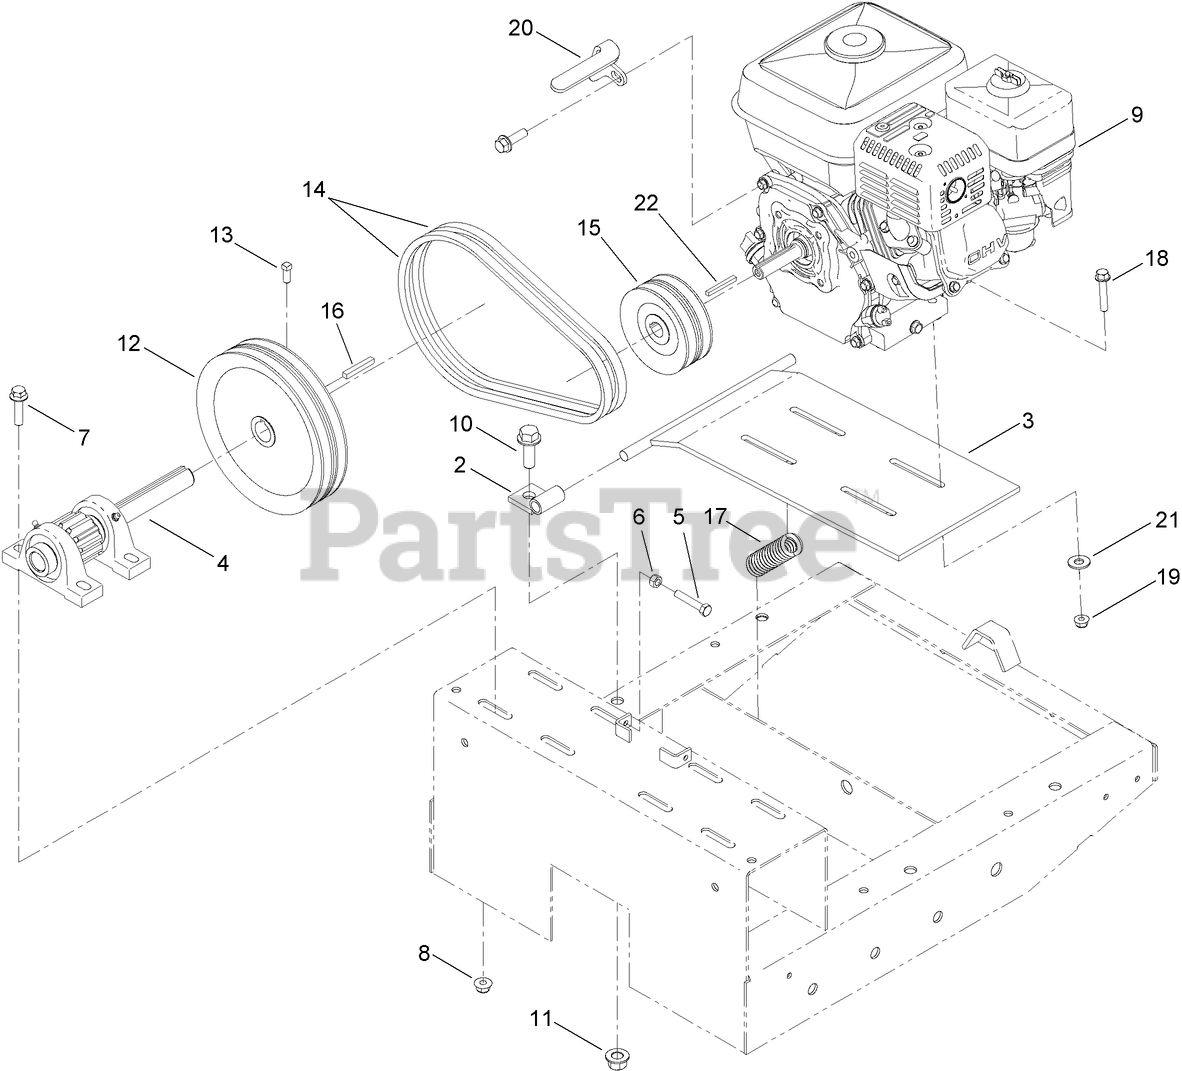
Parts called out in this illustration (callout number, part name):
2	MOUNT-MOTOR
3	BASE-MOTOR
4	PINION ASM
5	SCREW-HH
6	NUT-HEX
7	SCREW-HHF
8	NUT-HF, NI
9	ENGINE-HONDA, GX160
10	SCREW-HHF
11	NUT-LOCK
12	SHEAVE
13	SCREW-SET, SQH
14	BELT-V
15	SHEAVE
16	KEY-SQUARE
17	SPRING
18	SCREW-HWH
19	NUT-HF, NI
20	GUIDE-BELT
21	WASHER-FLAT
22	KEY-SQUARE
